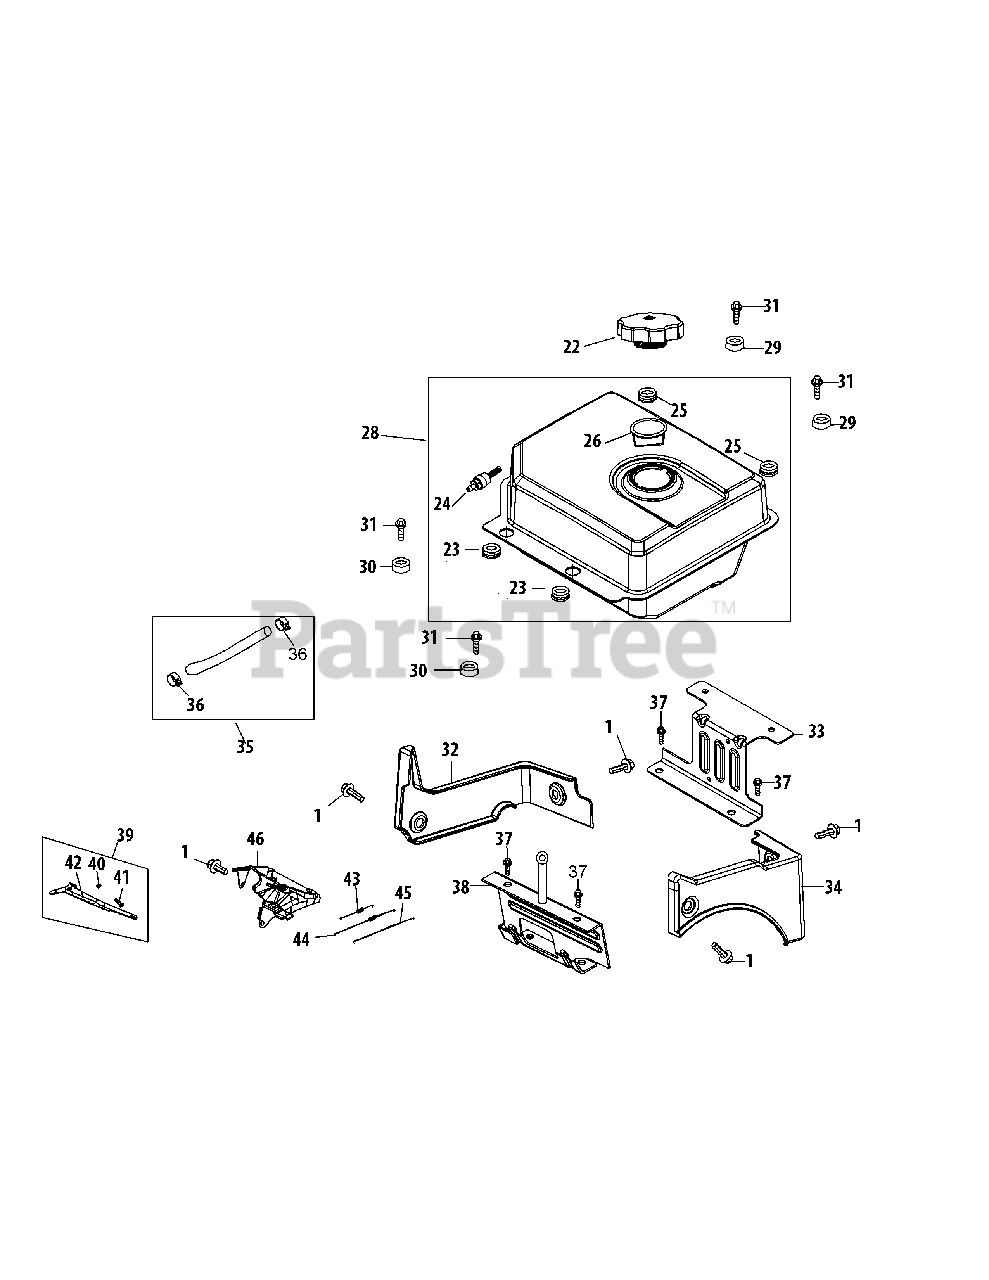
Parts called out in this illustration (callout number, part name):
22	FUEL CAP ASSEMBLY
23	VIBRATION PAD
24	DRAIN PIPE
25	VIBRATION PAD
26	FUEL LEVEL INDICATOR
28	FUEL TANK ASSEMBLY
29	BUSH, GAS TANK
30	BUSH, GAS TANK
31	BOLT M8×20
32	GOVERNOR COVER
33	REAR MAINTING BRACKET ASSY.
34	DECORATE COVER
36	FUEL HOSE CLAMP
37	BOLT M8×14
38	GAS TANK SUPPORT BRACKET
39	GOVERNOR LEVER
41	GOVERNOR ARM BOLT
42	GOVERNOR ARM
43	GOVERNOR SPRING
44	THROTTLE LINKAGE SPRING
45	THROTTLE LINKAGE
46	PRIMER BRACKET
